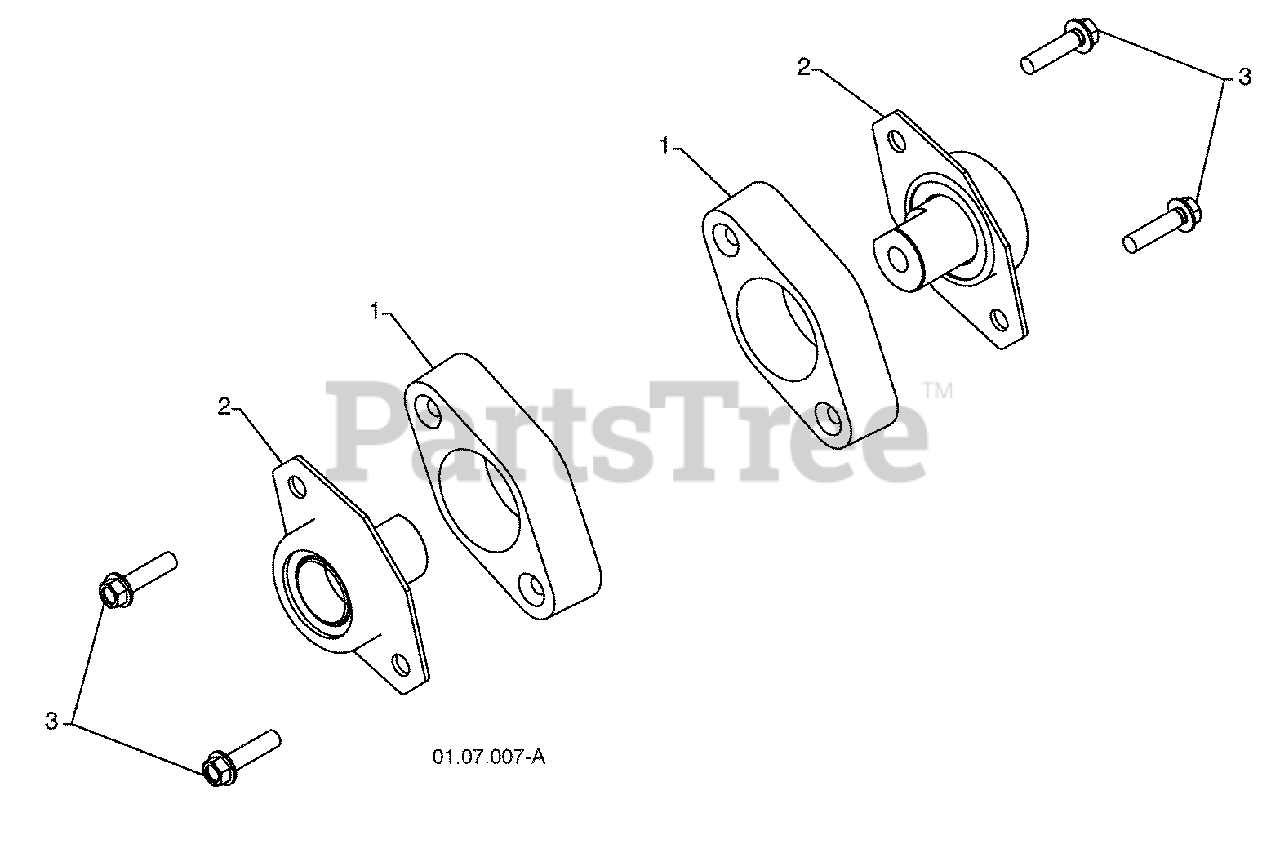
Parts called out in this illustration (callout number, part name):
1	PLASTIC RETAINER
2	AUGER BALL BEARING
3	SCREW 5/16-18 X 1.00
